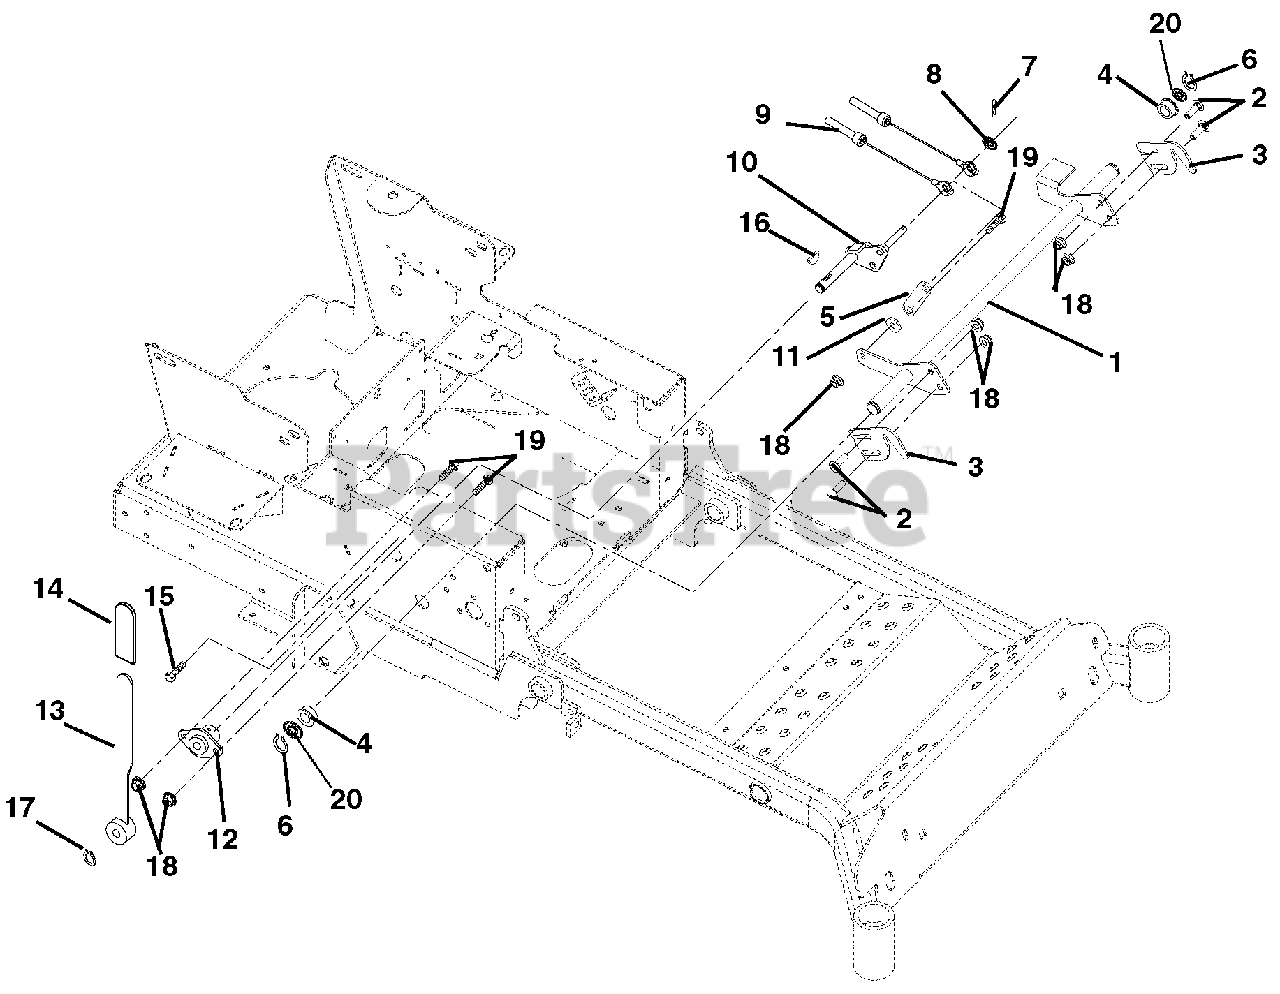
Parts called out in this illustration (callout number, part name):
1	Weldment, Neutral Lock Arm
2	Bolt, Round Head Square Neck .31-18 x 1.00 Grade 5
3	Neutral Lock Latch
4	Bushing, Flange .750 x 1.000 x .625 x 1.250
5	Plate, Neutral Interlock
6	Ring, Retaining-External .689 x .077
7	Pin, Hair-Internal .06 x .18 x .77
8	Washer, Flat-Steel .344 x .688 x .065
9	Cable, Brake Actuating
10	Weldment, Park Brake Arm
11	Bushing, Flange .325 x .499 x .26 x .88
12	Bushing, Flanged
13	Weldment, Parking Brake Lever
14	Grip, Parking Brake
15	Screw, Tapping .38-16 x 1.00 Hex Washer Head
16	Key, Woodruff .13 x .63
17	Ring, Retaining External .50 x .05
18	Nut, Nyloc Flange 5/16-18
19	Bolt, Hex .31-18 x 1.00 Grade 5
20	Washer, Flat-Steel .812 x 1.370 x .100
